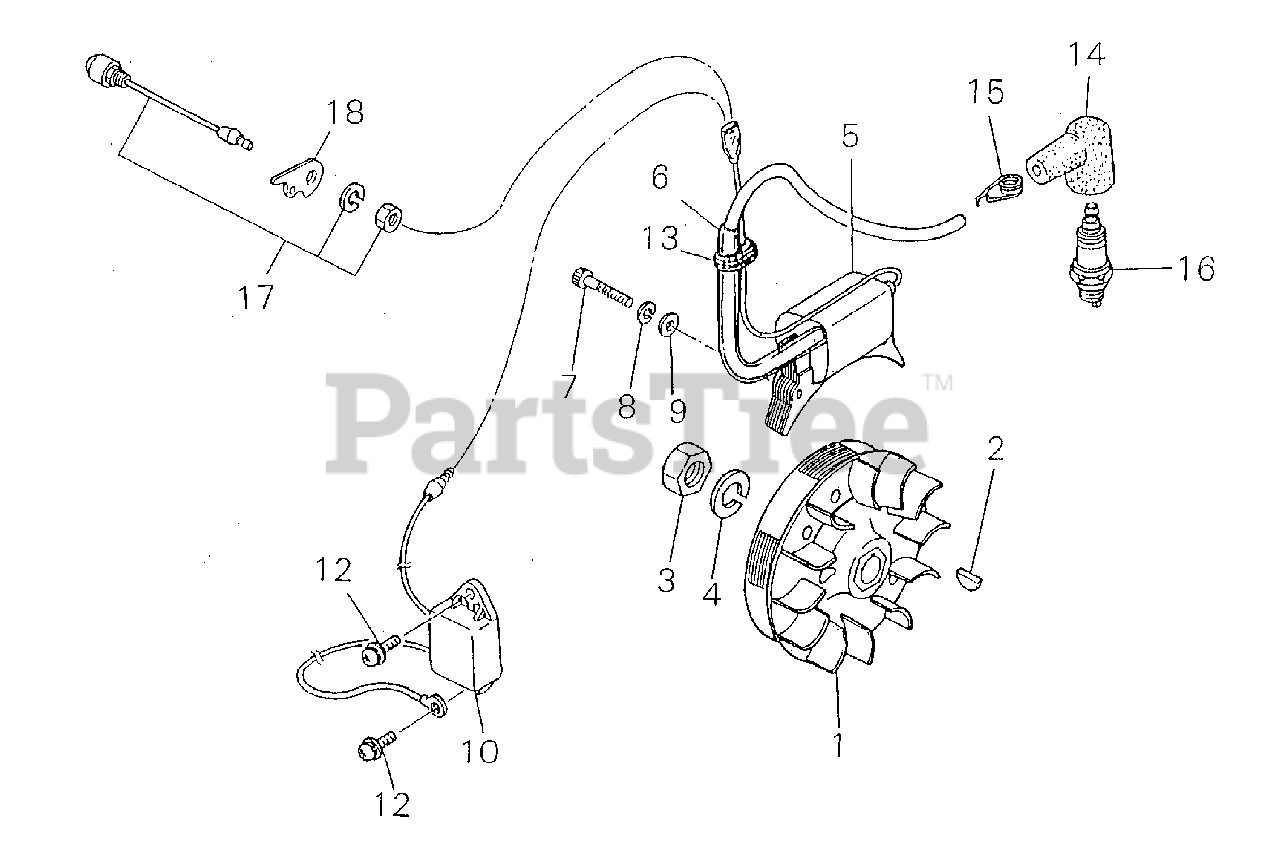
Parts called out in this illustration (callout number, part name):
1	FLYWHEEL
2	KEY, WOODRUFF 3×10
3	NUT
4	WASHER, SPRING 8
5	COIL, IGNITION
7	BOLT M4×24
8	WASHER, SPRING 4 MM
9	WASHER 4 MM
10	ELECTRONIC UNIT
12	SCREW M4×12
14	CAP, SPARK PLUG
15	TERMINAL, SPARK PLUG
16	SPARK PLUG - CJ8
17	SWITCH, ON-OFF
18	BRACKET
